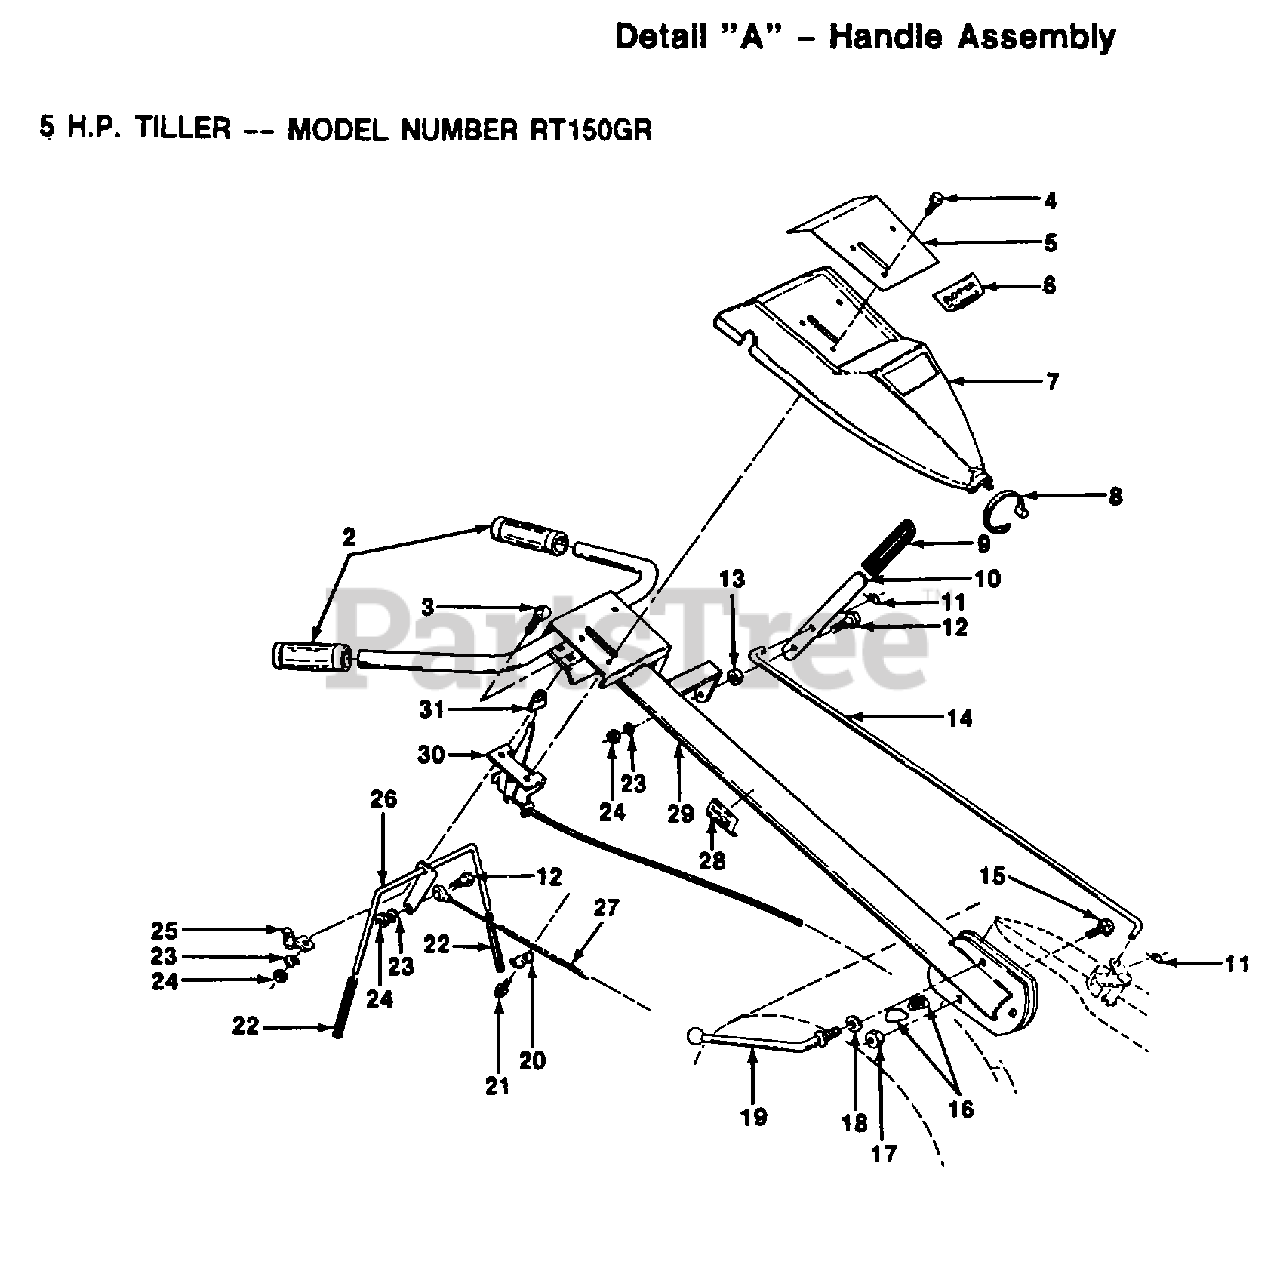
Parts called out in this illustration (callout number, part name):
3	BOLT
4	SCREW
6	DECAL - CONTROL PANEL
7	PANEL CONTROL
8	TIE CABLE CRT
9	GRIP T
10	SHIFT HANDLE CRT
11	RETAINER M
12	SHOULDER BOLT ST
13	GROMMET CRT
14	SHIFT ROD CRT
15	BOLT D
16	LOCK CRT
18	WASHER CRT
19	LEVER LOCK CRT
20	CONDIUT CLIP T
22	GRIP BAR CRT
23	LOCKWASHER
26	"ASSY CONTROL, BAR"
27	CABLE.CLUTCH.CRT
28	DECAL TI
30	THROTTLE CRT
31	KNOB CRT
